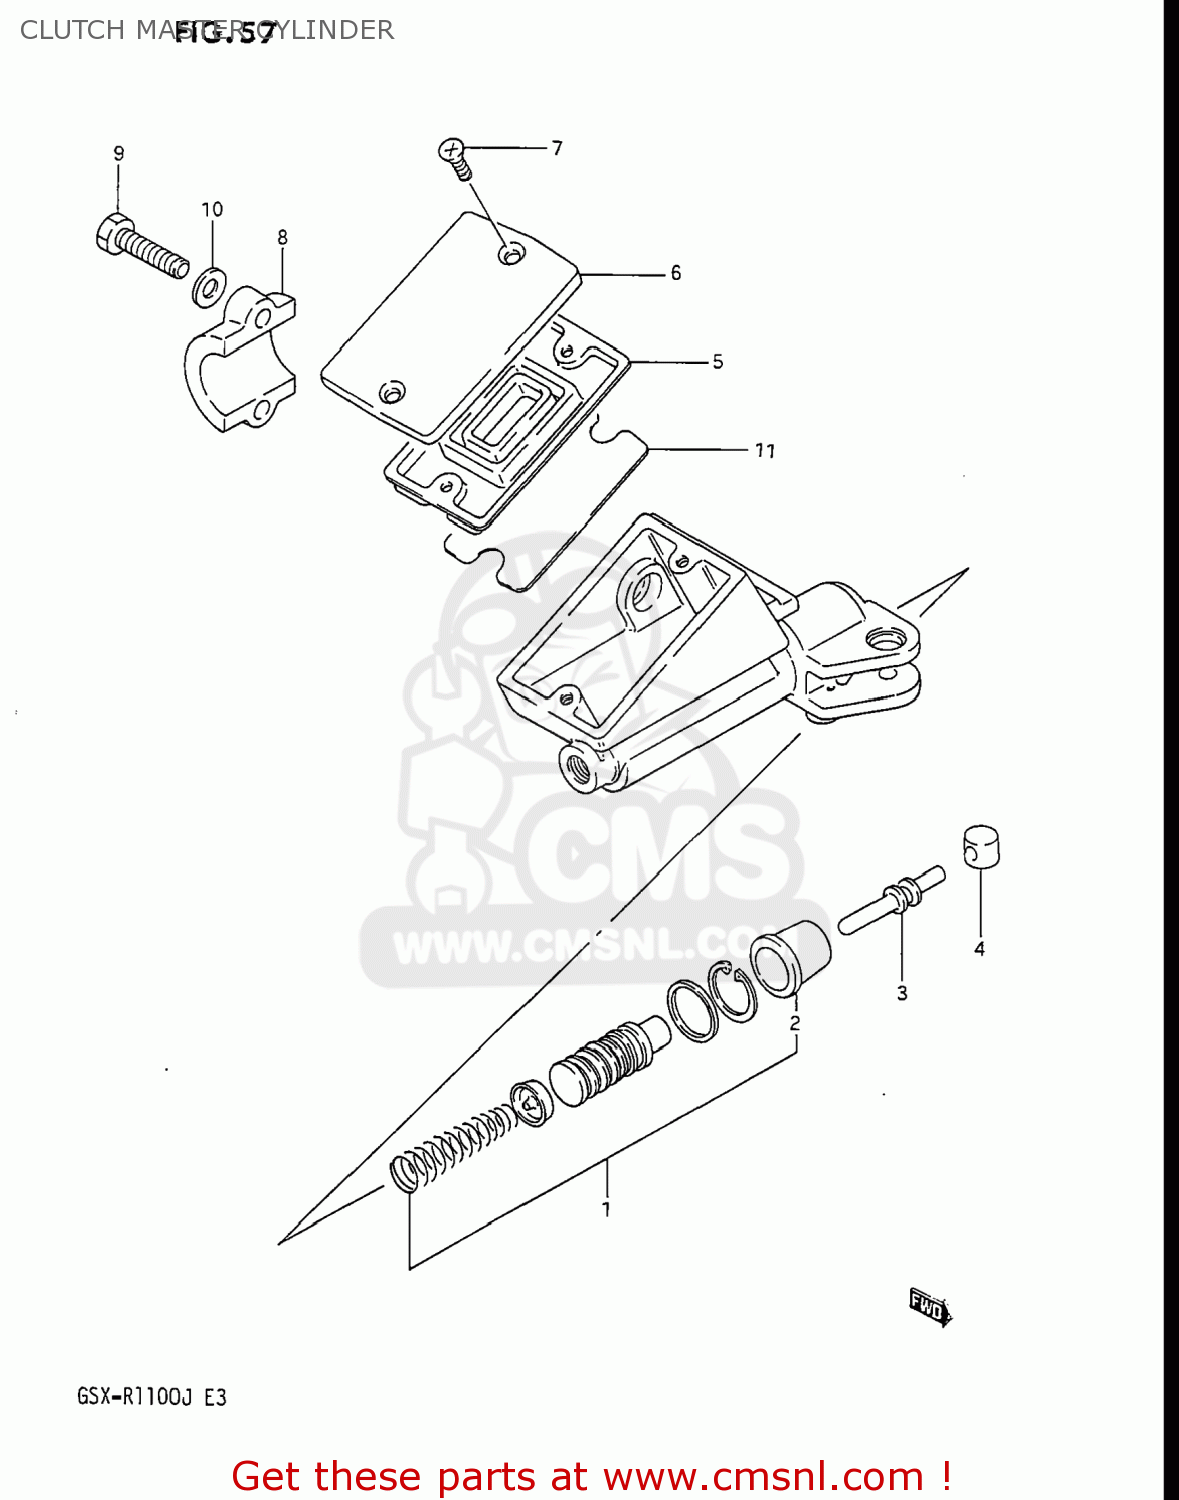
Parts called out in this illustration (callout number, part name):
1	PISTON & CUP SET
2	BOOT
3	ROD,PUSH
4	BUSH
5	6
6	CAP
7	SCREW
8	HOLDER,MASTER CYLINDER
9	BOLT
10	WASHER
11	FLOAT
